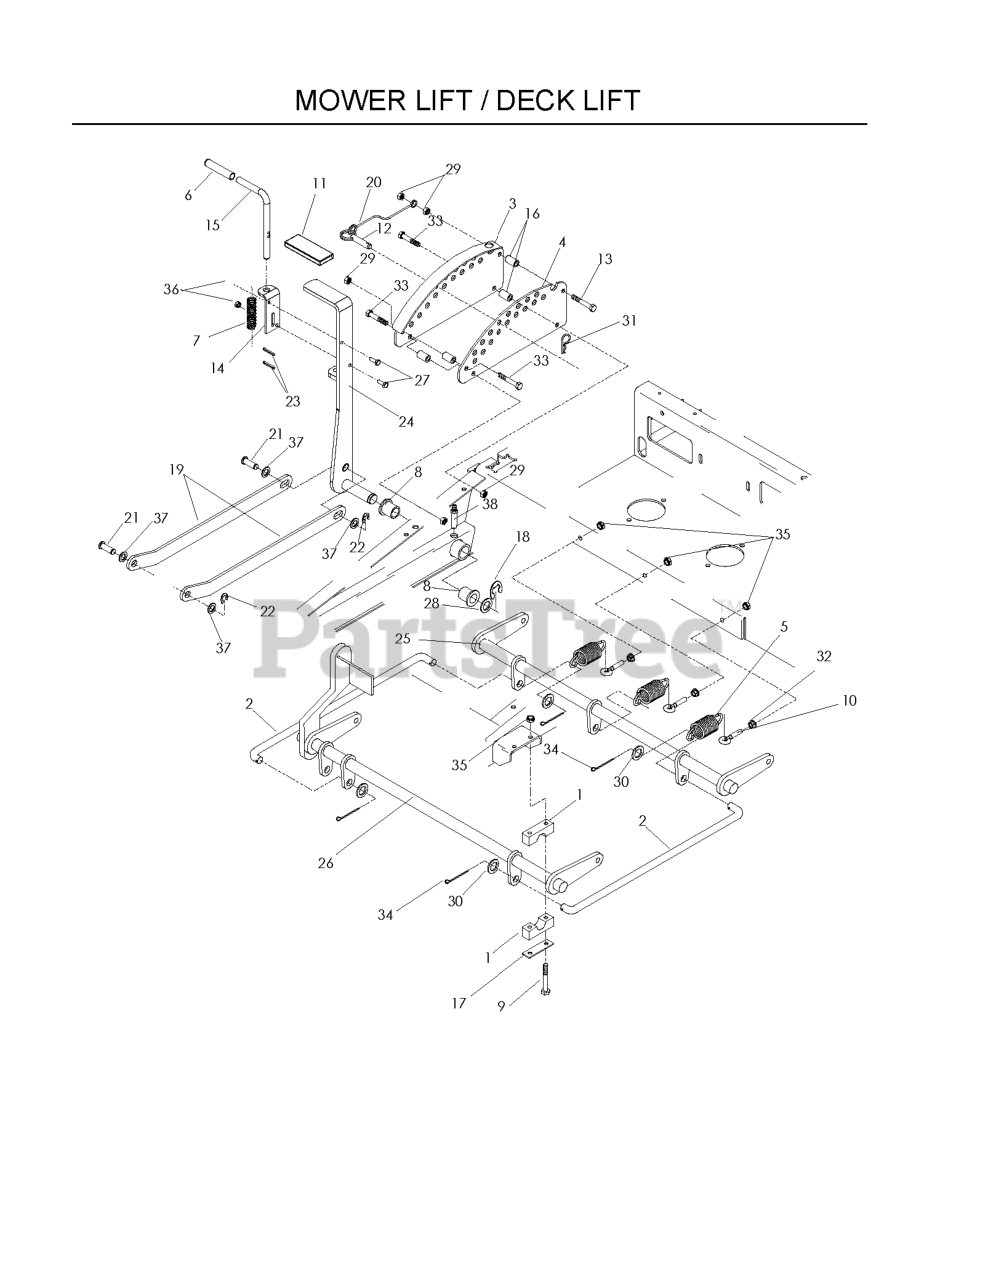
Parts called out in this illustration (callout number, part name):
1	PILLOW BLOCK
2	CONNECTING LINK
3	ADJ. PLATE WLDMNT
4	ADJ. PLATE PAINTED
5	DECK LIFT SPRING
8	BUSHING, FLANGED
9	HCS 5/16C X 2-3/4
10	EYEBOLT, RH
13	SCREW 3/8C X 2 3/4 HEX CAP
14	PIN MT, UPPER
16	DECK LIFT SPACER
17	REINFORCEMENT BAR
18	E-RING 7/8
19	LIFT LINKAGE,PAINTED
21	CLEVIS PIN
22	E-RING 5/8
24	LIFT LEVER WELDMENT
25	SHAFT LIFT REAR
26	LIFT SHAFT ASM, FRONT
27	HCS 1/4C X 3/4 HCS
28	BSHG .875 X 1.375 X .074 ZD
29	NUT 3/8-16 NYLOC
30	WASHER 5/8 FLAT
31	HAIRPIN #4
32	NUT 5/16C WHIZ
33	HCS 3/8C X 2 1/2
34	COTTER PIN
35	NUT 5/16 NYLOC
36	NUT 1/4C CENTER LOCK
38	GREASE ZERK LONG
